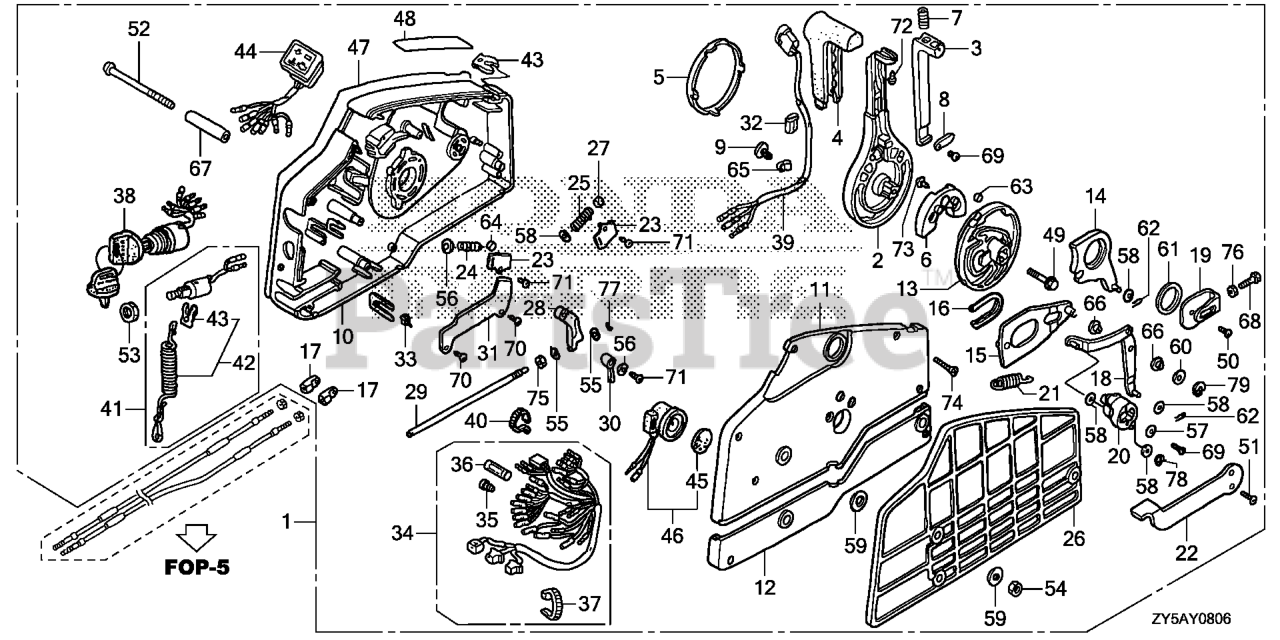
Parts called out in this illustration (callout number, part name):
1	BOX ASSY., REMOTE CONTROL (TROLLING CONTROL)(NHK MEC)
2	HANDLE, REMOTE CONTROL
3	LEVER, HANDLE LOCK
4	GRIP, REMOTE CONTROL HANDLE
5	CAP, HANDLE
6	BLOCK, NEUTRAL LOCK
7	SPRING, REMOTE CONTROL HANDLE
8	PLATE, LEVER SETTING
9	CLAMP, HARNESS
10	HOUSING, REMOTE CONTROL BOX (A)
11	HOUSING, REMOTE CONTROL BOX (B)
12	HOUSING, REMOTE CONTROL BOX (C )
13	WHEEL, CONTROL
14	ARM, SHIFT LINK
15	PLATE, SLIDING
16	COLLAR, SLIDING PLATE
17	PIVOT, SHIFT
18	ARM, LINK JOINT
19	BRACKET, LINK JOINT
20	WHEEL, ACCELERATOR
21	SPRING, ACCELERATOR WHEEL
22	LEVER, IDLE
23	PLATE, SPRING SETTING
24	SPRING, SHIFT CLICK
25	SPRING, CHOKE RETURN
26	SPACER, REMOTE CONTROL BOX
27	SPACER, CLICK SPRING
28	BLOCK, THROTTLE FRICTION
29	BOLT, FRICTION
30	SPACER, NEUTRAL SWITCH
31	CLAMP, POWER TILT CORD
32	PIPE, HARNESS GUIDE
33	SPACER, CABLE CLAMP
34	CABLE ASSY., REMOTE CONTROL (B) (FOR 4-LED)
35	PLUG, CONNECTOR (INNER) (TROLLING CONTROL)
36	PLUG, CONNECTOR (OUTER) (ENGINE NO.)
37	TIE, CABLE (NATURAL 2.4X92) Use up to Frame SN 1300359.
38	SWITCH ASSY., COMBINATION (SINGLE) (DUAL)
39	SWITCH ASSY., POWER TRIM-TILT
40	BAND (BLACK 3.5X140)
41	SWITCH ASSY., EMERGENCY STOP
42	WIRE, EMERGENCY (SINGLE) (DUAL)
43	CLIP, EMERGENCY LOCK
44	LAMP ASSY., INDICATION
45	PLATE, TURN SIGNAL BUZZER DUAL QTY = (2) (SINGLE)
46	BUZZER, WARNING DUAL QTY = (2) (SINGLE)
47	PLATE, REMOTE CONTROL (COUTION COLOR=RED & YELLOW)
48	MARK, FAST IDLE
49	BOLT, FLANGE (8X35) Use from Frame SN 4800713.
50	SCREW, PAN (6X10)
51	SCREW, FLAT (5X12) Use from Frame SN 4800713.
52	SCREW (6X95)
53	NUT, HEX. (16MM) DUAL QTY = (2) (SINGLE)
54	NUT, HEX. (6MM)
55	WASHER, PLAIN (4MM) Use from Frame SN 4800713.
56	WASHER, PLAIN (5MM)
57	WASHER, PLAIN (5MM)
58	WASHER, PLAIN (6MM) Use from Frame SN 4800713.
59	WASHER (6MM)
60	WASHER, PLAIN (8MM) Use from Frame SN 4800713.
61	WASHER (28MM)
62	PIN, LOCK (6MM)
63	PIN (6X6)
64	ROLLER, CLICK
65	CLIP, WIRE HARNESS (6.3MM)
66	COLLAR, LINK JOINT
67	COLLAR, DISTANCE (6X10X43.5)
68	BOLT, HEX. (5X16)
69	SCREW, PAN (5X10)
70	SCREW, TAPPING (5X8) (FOR SILVER MUFFLER)
71	SCREW, TAPPING (5X10)
72	SCREW, TAPPING (5X12)
73	SCREW, TAPPING (6X16)
74	SCREW, TAPPING (5X25)
75	NUT, HEX. (6MM)
76	NUT, HEX. (5MM)
77	E-RING (3MM)
78	E-RING (4MM)
79	E-RING (7MM)
